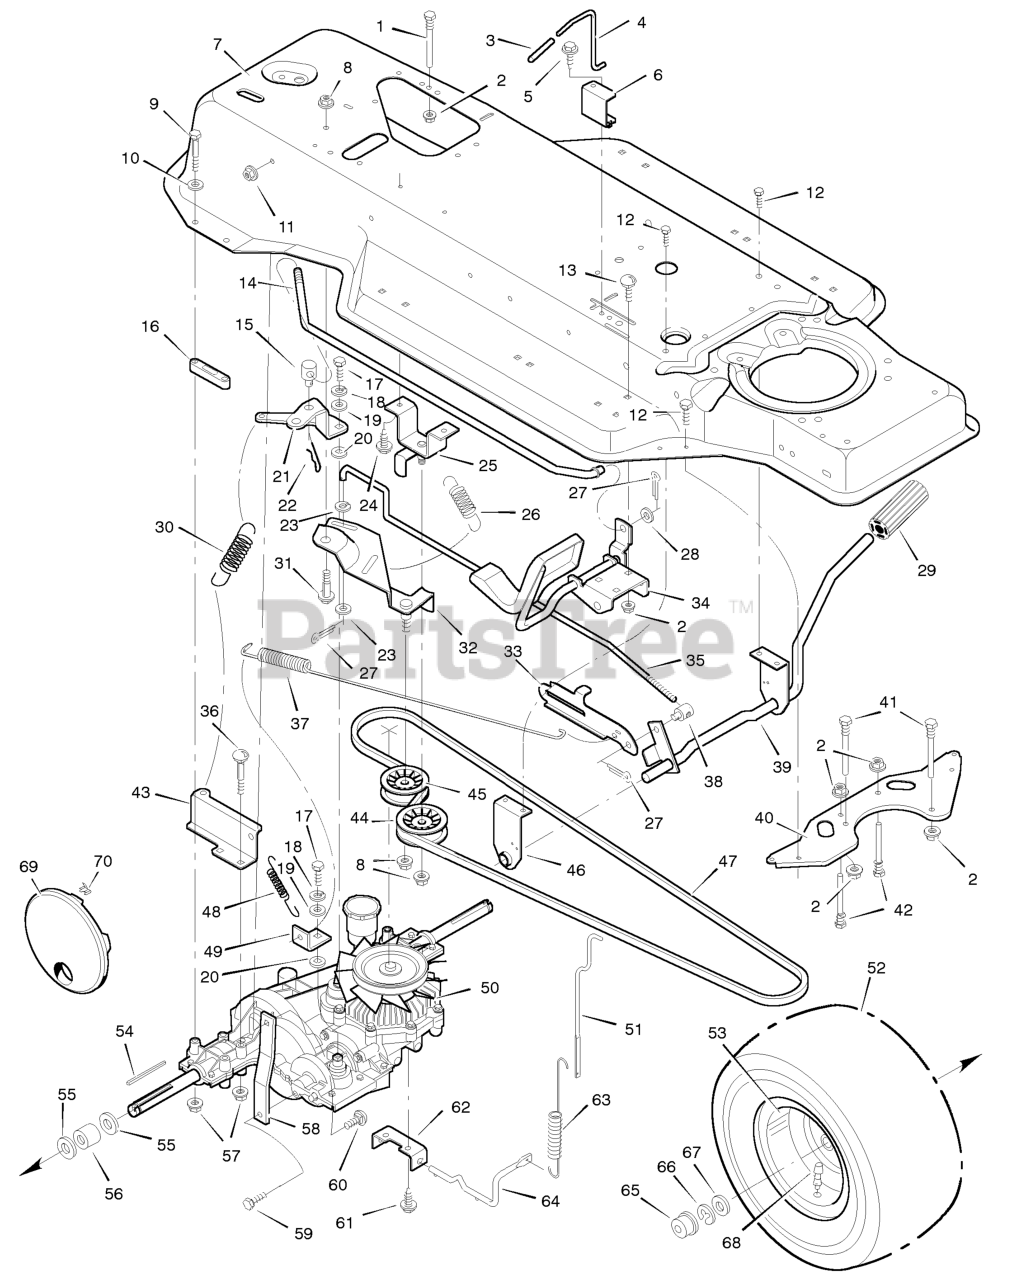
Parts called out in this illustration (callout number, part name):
1	Guide, Belt
2	Nut, Flange
4	Rod, Parking Brake
6	Bracket, Guide
7	Frame Assembly
8	Nut, Flange
10	Washer
11	Nut, Flange
13	Bolt, Carriage
14	Rod, Control
15	NUT, Adjusting, 1/2-13
16	Spacer, Hydro
18	Lockwasher
21	Lever, Control
22	Hair Pin
23	Washer
25	Idler Mount Assembly
26	Spring, Extension
27	Cotter Pin
29	Pedal
30	Spring, Extension
31	Shoulder Bolt
32	Idler Bracket Assembly
33	Latch, Parking Brake
34	Pedal Assembly
35	Clutch Rod
36	Carriage Bolt
37	Spring, Extension
38	Nut, Adjusting
39	Pedal Lever Assembly
40	Plate, Belt Guide
41	Screw, Guide
42	Screw, Guide
43	Bracket, Spring Mount
44	Idler Pulley
45	Idler Pulley
46	Support, Pedal
47	V- Belt
48	Spring, Extension
49	Lever, Brake
50	Transaxle **
51	Rod, Dump Valve
52	Wheel & Tire Assembly
53	Tire *
54	Square Key
56	Spacer, Wheel
57	Nut, Flange
58	Strap, Torque
60	Carriage Bolt
62	Bracket, Dump Valve
63	Spring, Extension
64	Rod, Dump Valve
65	Hub Cap
68	Valve Stem
69	Disc, Wheel
70	Clip, Retainer
